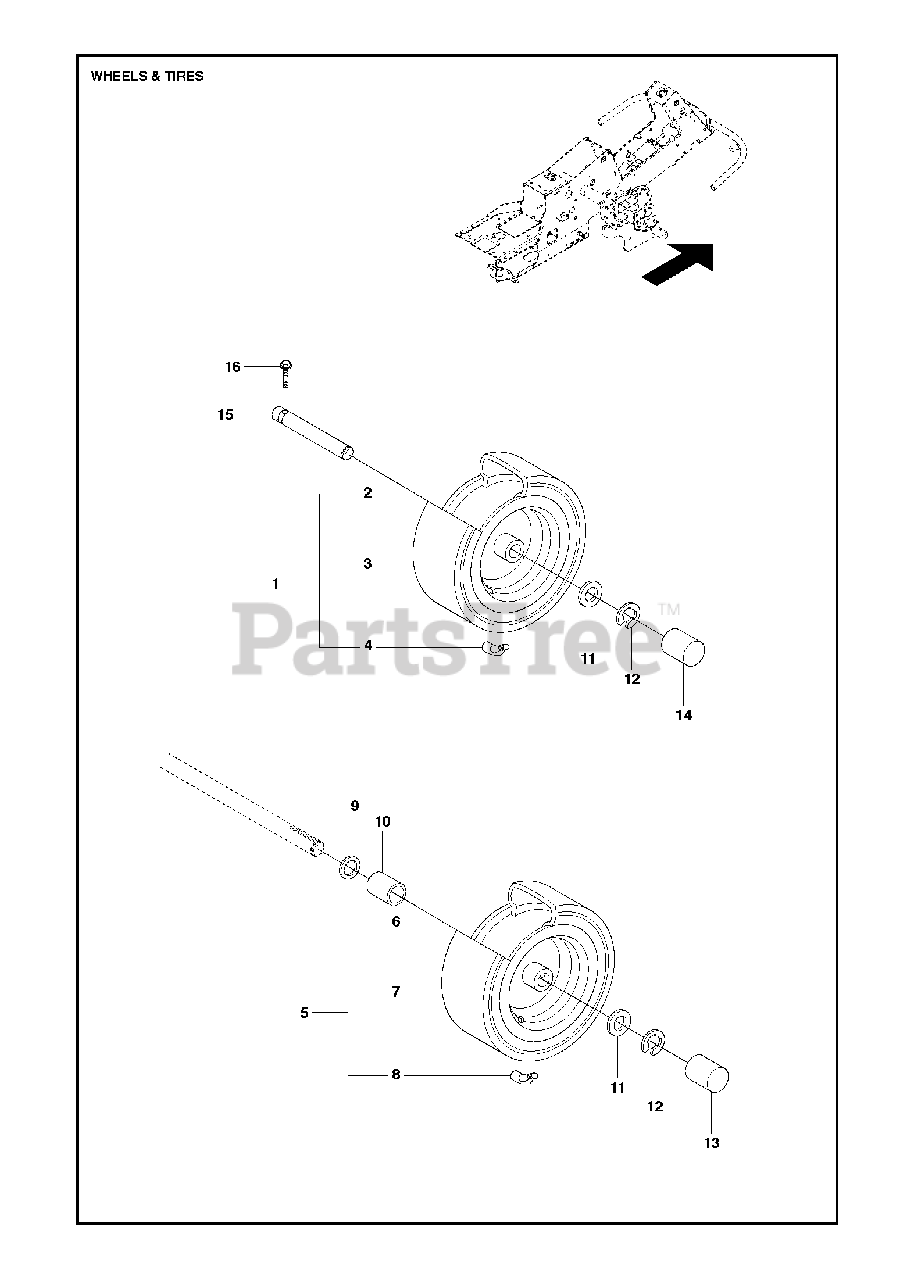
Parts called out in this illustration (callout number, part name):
6	RIM
10	SPACE SLEEVE
12	RETAINING RING
16	BOLT FLANGE - M8X40\
